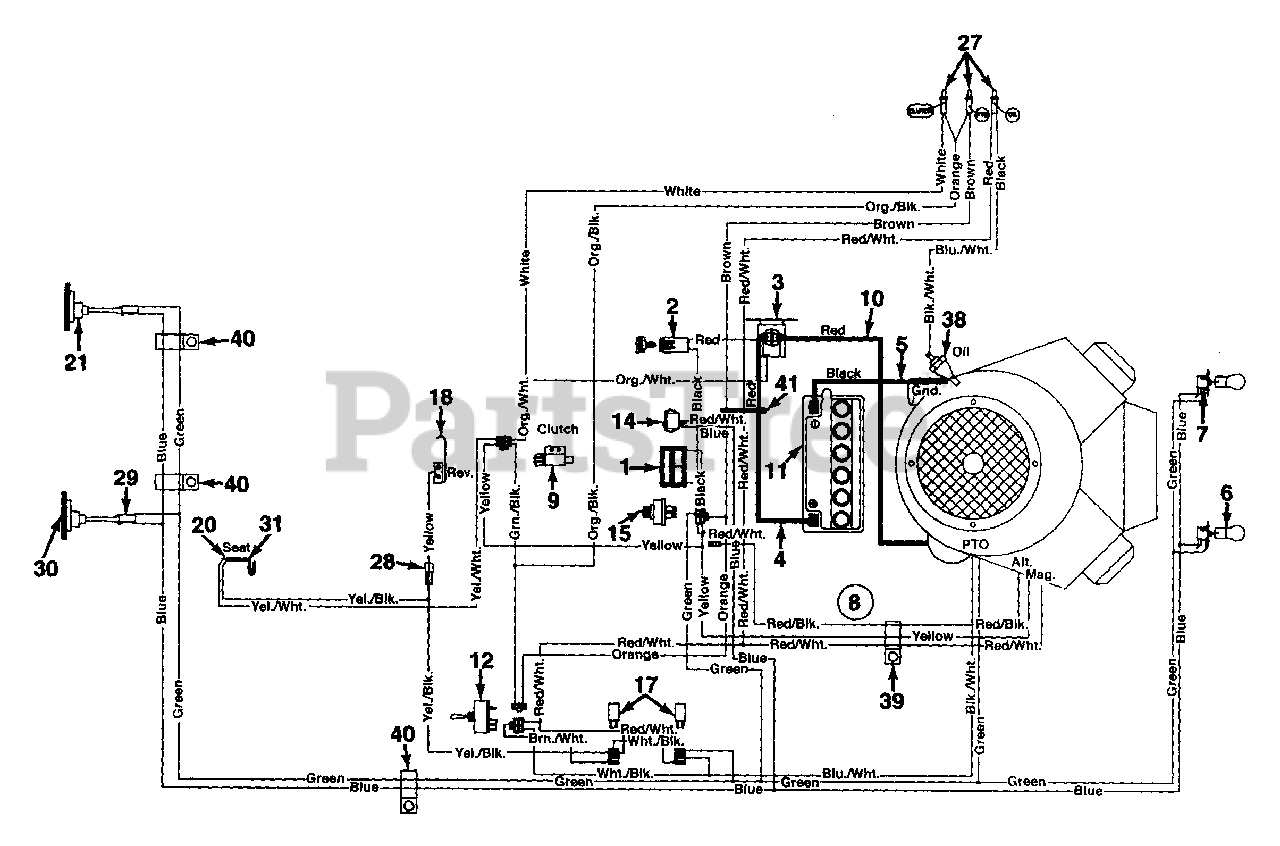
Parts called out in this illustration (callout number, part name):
1	Ammeter
2	Fuse 20 Amp
3	Solenoid
4	Wire
5	6 Ga. Red Wire 20" Lg.
6	Bulb
7	Socket
8	Wire Harness
9	Safety Switch (Clutch)
10	6 Ga. Black Wire
11	Battery (275 Cold Crank Amps)
12	Switch (PTO)
14	Light Switch
15	Ignition Switch
17	Relay
18	Spring Lever
20	Safety Switch (Seat)
21	Tail light
27	Bulb
28	Transmission Ext. Wire
29	Tail light Harness
30	Bulb
31	Safety Switch (Seat)
38	Oil Pressure Switch
39	Clamp 9/16" Dia.
40	Clamp 5/16" Dia.
41	Cable Tie
